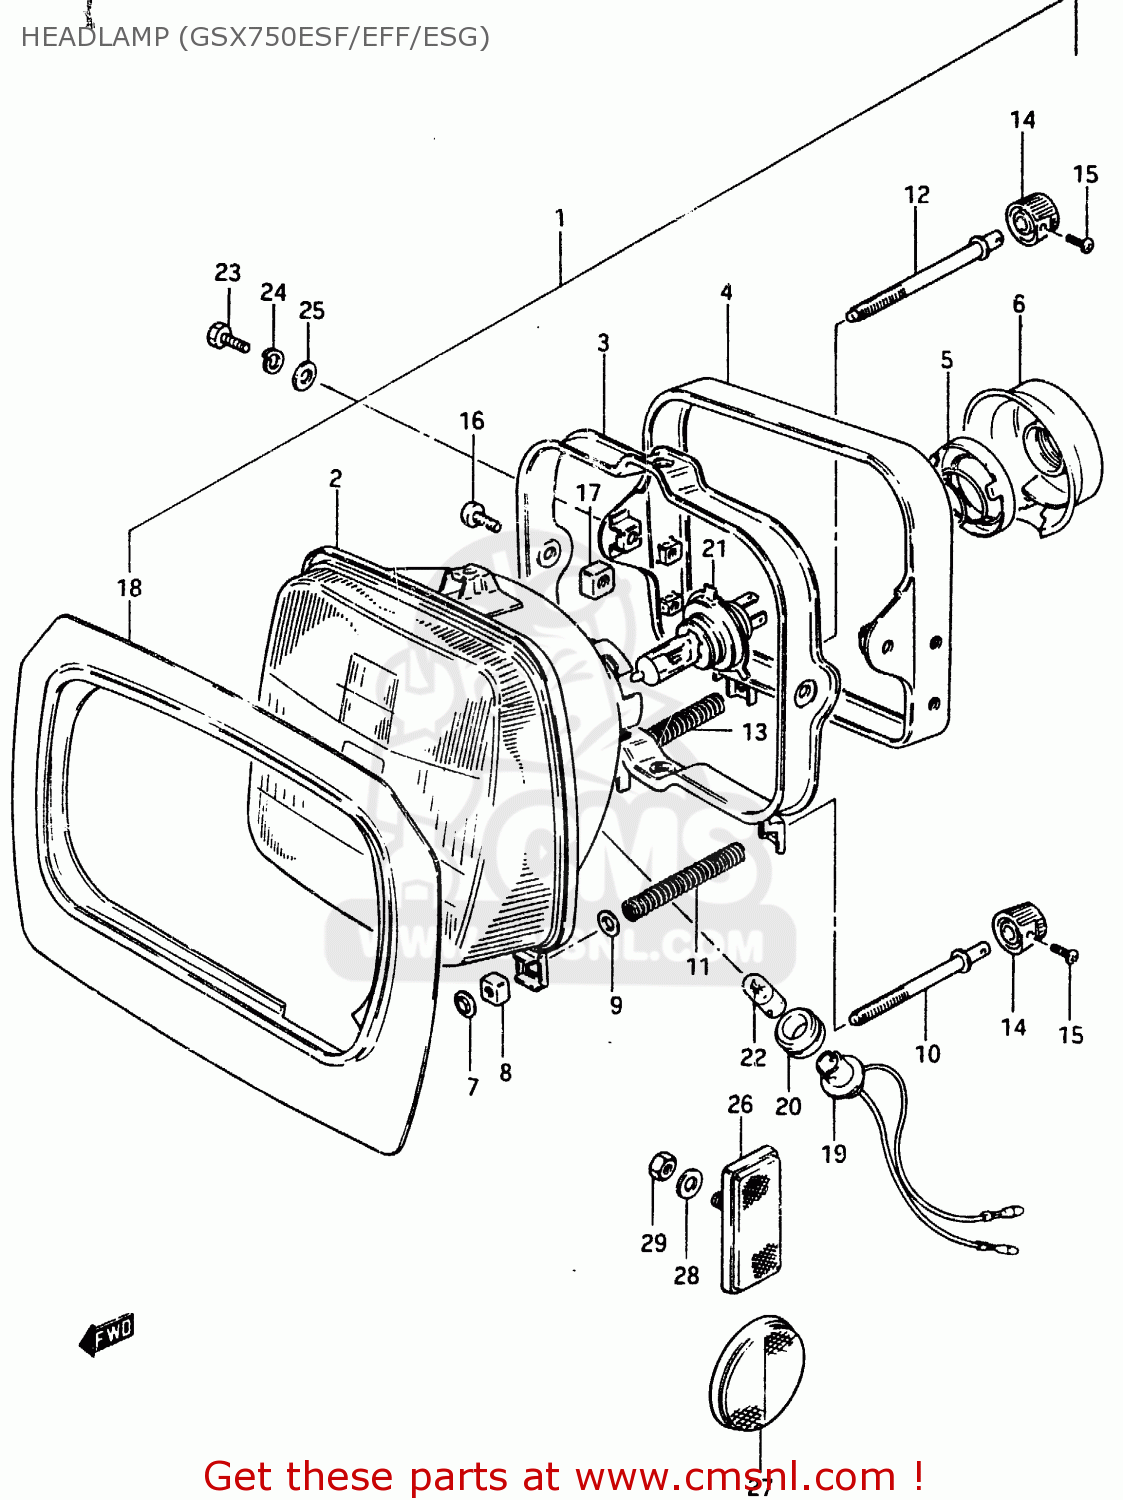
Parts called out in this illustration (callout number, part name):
1	HEADLAMP ASSY
2	UNIT
3	RING,MOUNTING
4	HOUSING,LAMP UNIT
5	HOLDER
6	COVER,HEADLAMP SOCKET
7	NUT,HEADLAMP ADJUSTER
8	NUT,HEADLAMP ADJUSTER
9	WASHER
10	SCREW,HEADLAMP ADJUST
11	SPRING
12	SCREW,ADJUSTING
13	SPRING
14	KNOB,ADJUSTER
15	SCREW
16	SCREW
17	NUT
18	SHADE
19	SOCKET
20	JOINT,RUBBER
21	BULB(12V60/55W,H4)
22	BULB(12V4W)
23	BOLT,M6X1X20
24	WASHER,LOCK
25	WASHER, LOWER
26	REFLEX REFLECTOR, FRONT SIDE
27	REFLECTOR,REFLEX FR
28	WASHER,5MM
29	NUT ,5MM
